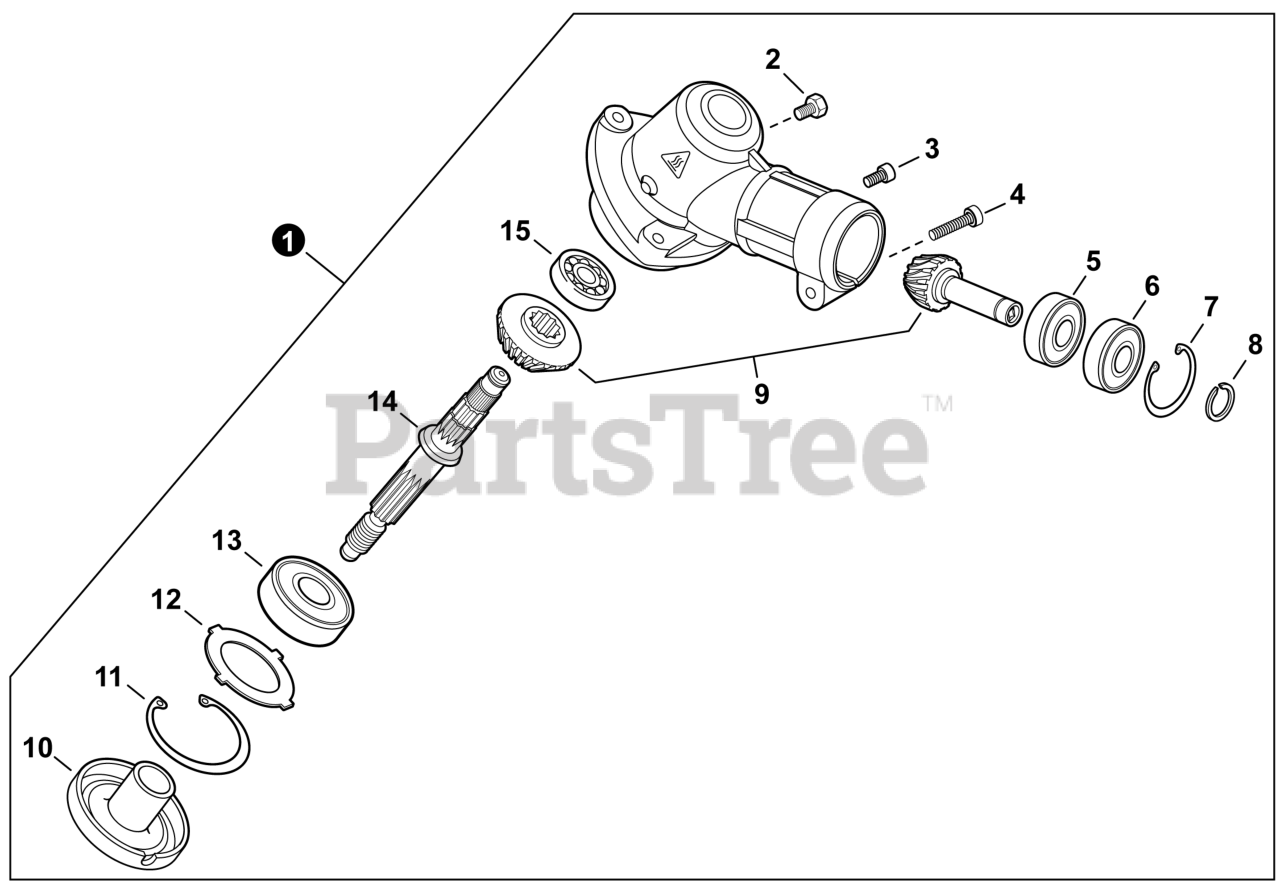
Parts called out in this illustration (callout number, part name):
1	GEAR CASE ASSY
2	BOLT M8×8
3	BOLT, TORX 5×12
4	BOLT, TORX 5×25
5	BEARING, BALL 609A
6	BEARING, BALL 609ZA
7	RING, SNAP Ø25
8	RING, SNAP Ø9
9	GEAR SET
10	PLATE, ADAPTOR - UPPER
11	RING, SNAP Ø32
13	BEARING, BALL 6201
14	SHAFT, GEAR
15	BEARING, BALL 629A
